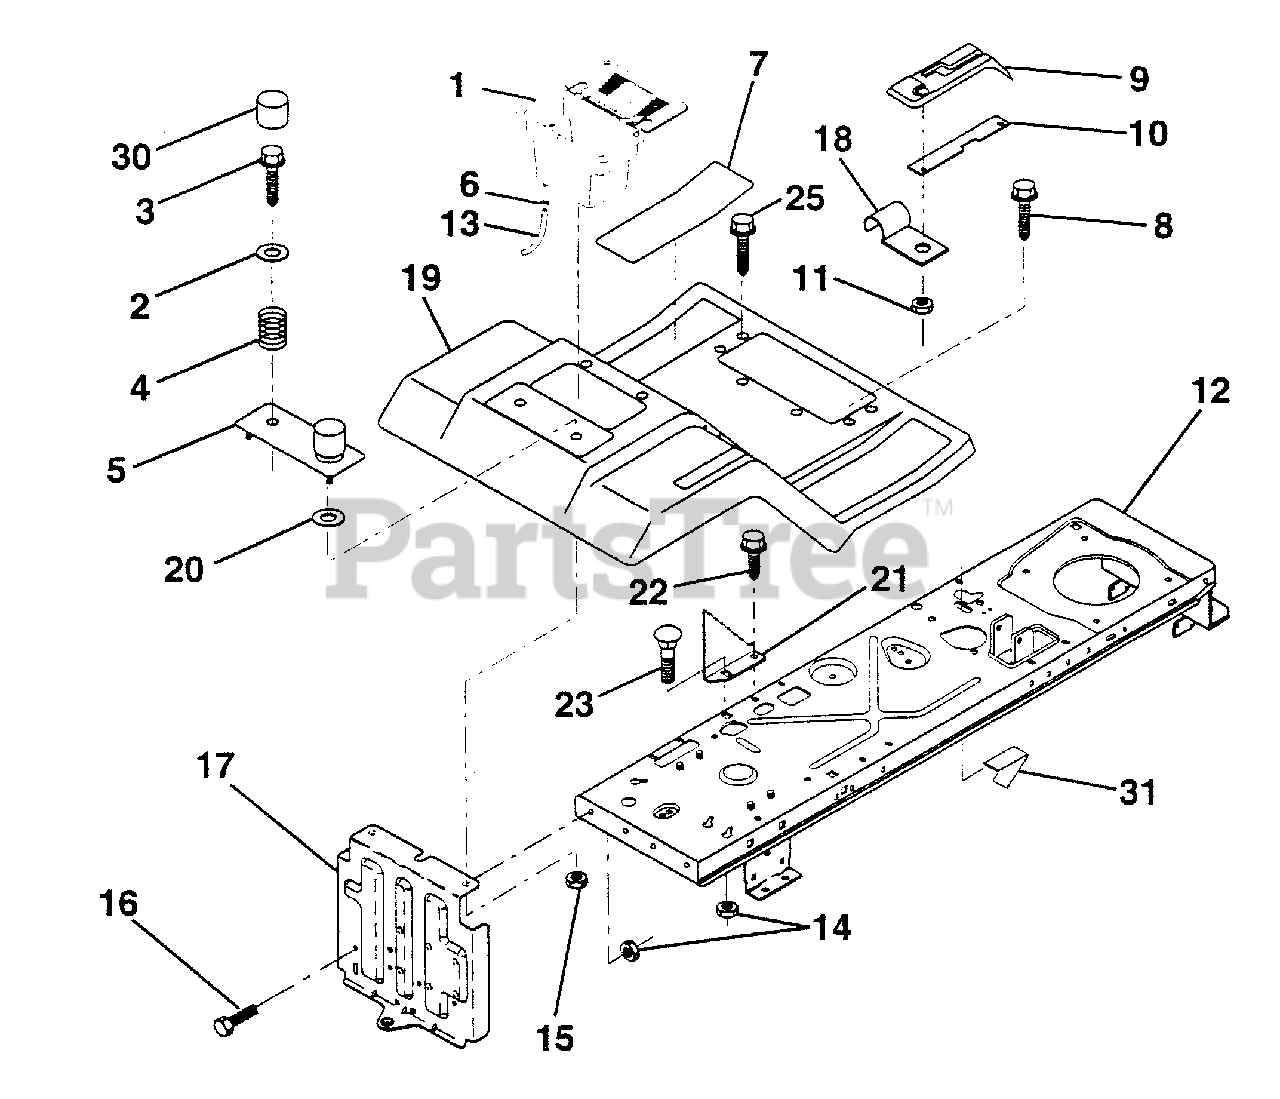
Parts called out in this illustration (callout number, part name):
1	Case Asm. Battery
2	Washer 13/32 x 1-1/4 x 12 Ga.
3	Screw Thdrol. 3/8-16 x 3/4
4	Spring seat
5	Plate Asm. Pnt Battery Fender
6	Clamp Hose Olive
7	Pad Footrest Rubber Deluxe
8	Screw Thdrol. 5/16-18 x 3/4
9	Console Shf. 6sp W/Ign.
11	Nut Self Thd. Wsh-Hd 1/4
12	Chassis Asm. Weldment
13	Tube Plastic
14	Nut Lock Hex W/Ins. 5/16-18
15	Nut Keps Hex 1/4-20
16	Bolt Hex Hd. 5/16-18 x 3/4
17	Drawbar Asm.
18	Clip Insulated
19	Fend/Foot Asm. Pnt Shf. Fnd.
20	Washer 9/32 x 7/8 x 13 Ga.
21	Bracket Stop Depth
22	Screw Thdrol 5/16-18 x 1/2
23	Bolt Rdhdsqnk. 5/16-18 x 3/4
25	Scr-Hex Wsh Rol 5/16-18 x 1
30	Cap Spring
31	Switch Actuator
